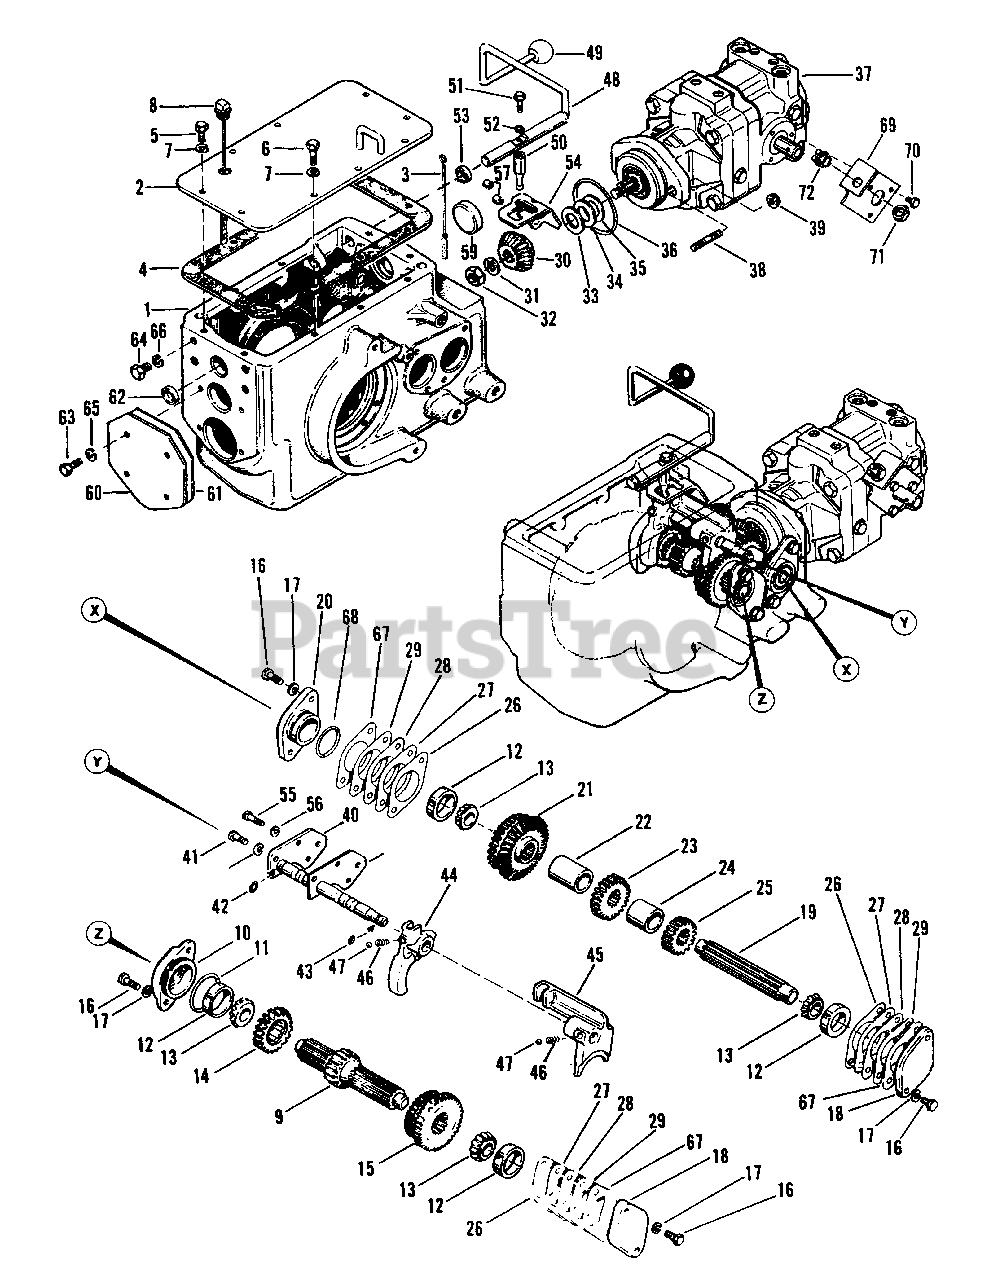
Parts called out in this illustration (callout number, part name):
1	Differential Case
2	Cover Assembly
5	Hex Capscrew, 3/8"-16 x 3/4" lg.
6	Hex Capscrew, 3/8"-16 x 1" lg.
7	Lockwasher, 3/8"
8	Dip Stick Assembly
9	Sliding Gear Shaft
10	Bearing Cap
13	Bearing Cone
14	Gear, 20T
15	Lo and 2nd Gear
16	Hex Capscrew, 3/8"-16 x 7/8" lg.
17	Lockwasher, 3/8"
18	Bearing Cap
19	Input Shaft
20	Bearing Cap
21	Bevel Gear Assembly
23	Gear, 23 T
25	Gear, 18 T
26	Shim, .002
27	Shim, .003
28	Shim, .005
29	Shim, .010
30	Bevel Pinion, 24 T
32	Hex Jam Nut, 1/2"-20
33	Shim, .002
34	Shim, .003
35	Shim, .005
37	Hydro. Motor w/pump
39	Whiz Lock Nut
40	Shift Shaft Assembly
41	Hex Capscrew, 3/8"-16 x 3/4" lg.
44	Shift Fork HI
45	Shift Fork Lo, 2nd
48	Shifter Shaft Assembly
50	Shift Stem
51	Hex Capscrew, 5/16"-18 x 1" lg.
52	Lockwasher, 5/16"
54	Shift Guide
55	Hex Capscrew, 1/4"-20 x 1 " lg.
56	Seal Washer
59	Expansion Plug (Mfg. Nos. 920 & 953)
60	Rear Cover (Mfg. Nos. 920 & 953)
61	Gasket (Mfg. Nos. 920 & 953)
62	Expansion Plug
63	Hex Capscrew, 3/8"-16 x 1" lg. (Mfg. Nos. 920 & 953)
64	Hex Capscrew, 7/16"-14 x 3/4" lg.
65	Lockwasher, 3/8" (Mfg. Nos. 920 & 953)
66	Lockwasher, 7/16
67	Shim Pack, .030
69	Mounting Bracket
70	Washer Head Screw, 1/4"-20 x 1/2" lg.
71	Nut, 9/16"-18
